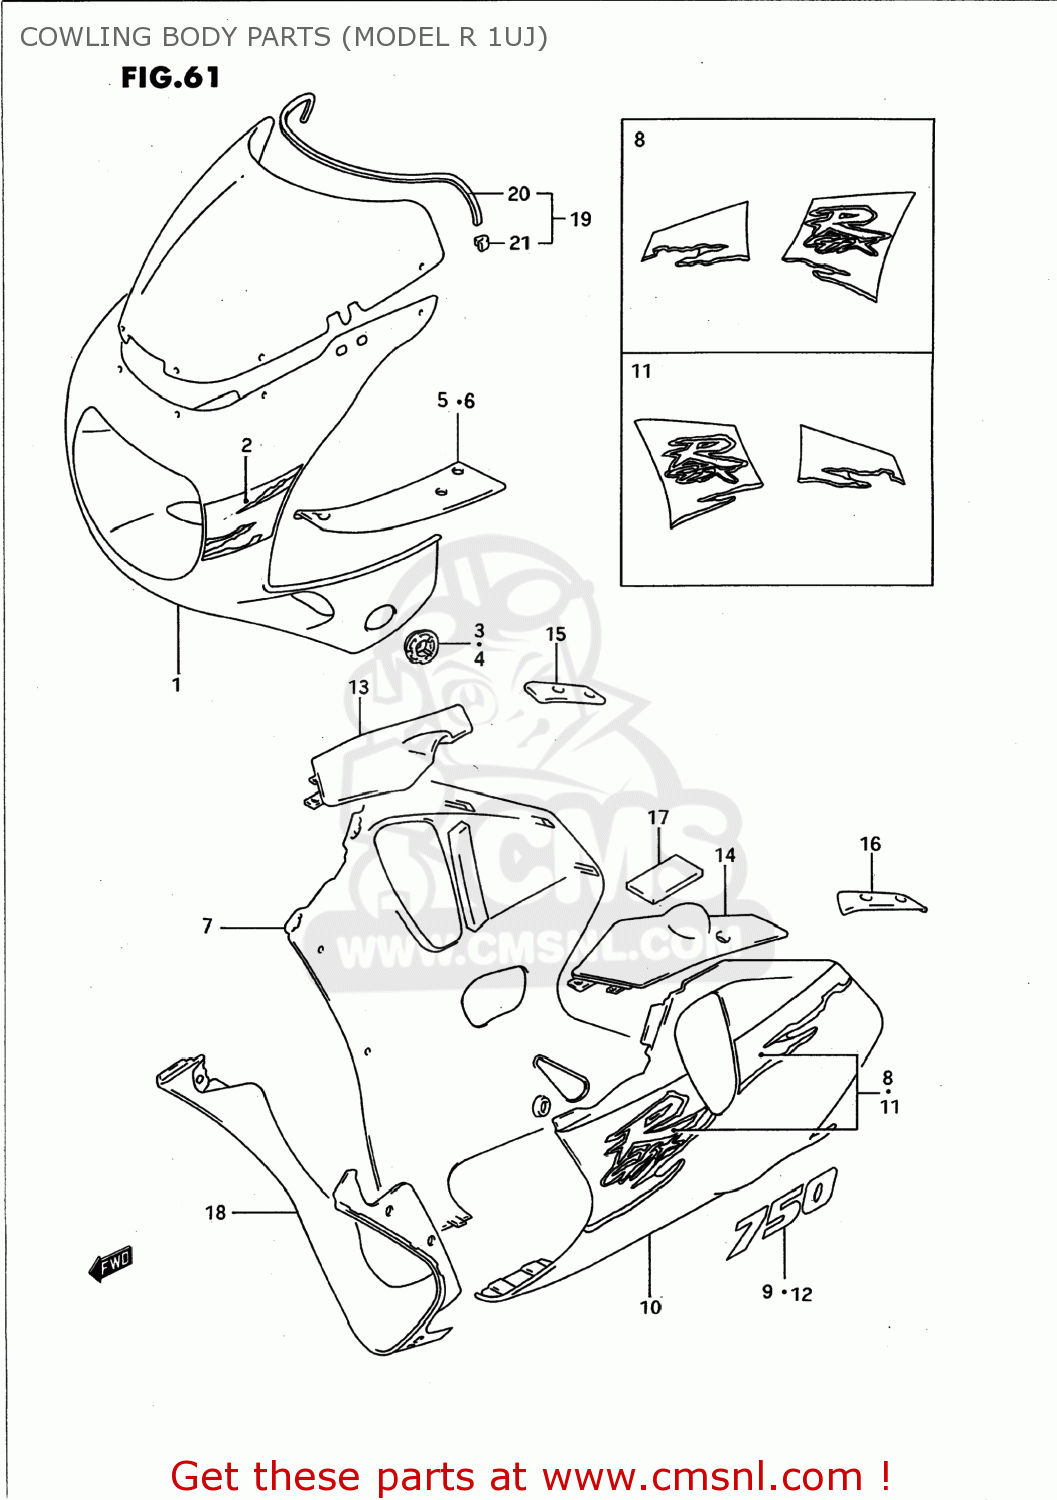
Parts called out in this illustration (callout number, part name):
1	COWLING ASSY,BODY
2	TAPE SET,COWL BODY
3	PLATE,TURN SIGNAL,RIGHT
4	PLATE,TURN SIGNAL,LEFT
5	PANEL,COWLING,UPPER,RIGHT
6	PANEL,UPPER,LEFT
7	COWLING ASSY,UNDER,R
8	TAPE SET,COWL UNDER,R
9	EMBLEM,COWLING,UNDER
10	COWLING ASSY,UNDER,L
11	TAPE SET,COWLING,UNDER
12	EMBLEM,COWLING,UNDER
13	PANEL,LWR FR,R
14	PANEL,LWR FR,L
15	PANEL,LWR RR,R
16	PANEL,LWR RR,L
17	CUSHION,PANEL
18	COWLING,UNDER CTR
19	WINDSCREEN SET
20	MOLDING WINDSCREEN
21	CLIP,WINDSCREEN MOLDING
